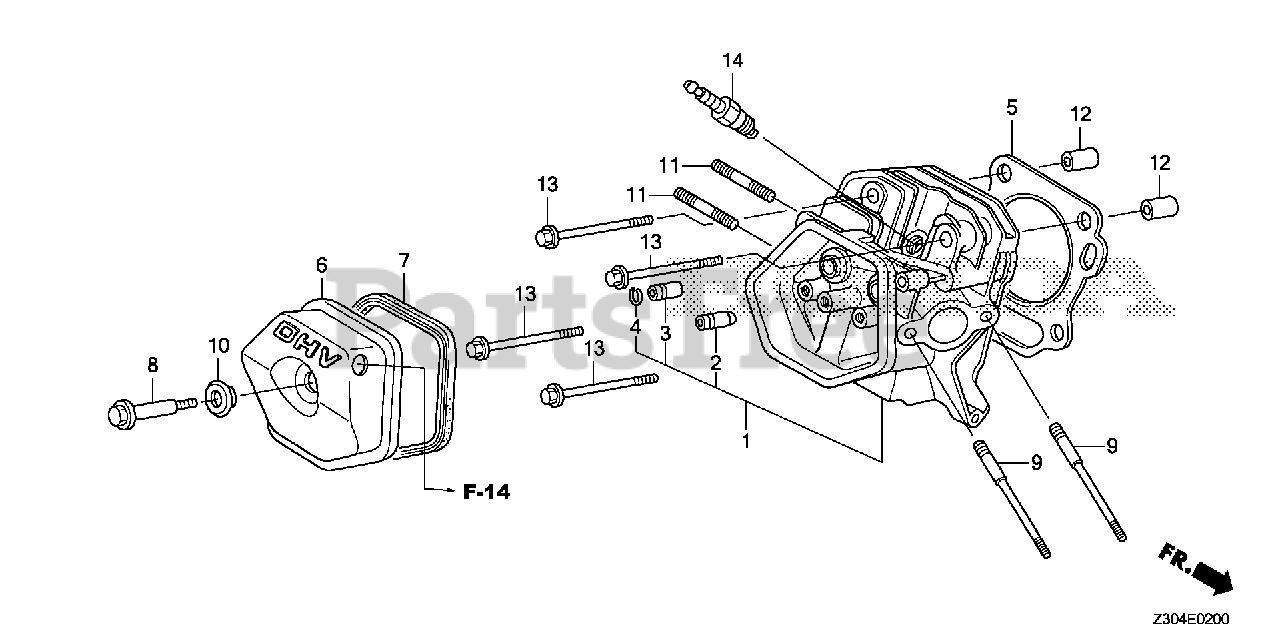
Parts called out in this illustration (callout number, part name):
1	CYLINDER HEAD
2	GUIDE, VALVE (OVER SIZE)
3	GUIDE, EX. VALVE (OVER SIZE)
4	CLIP, VALVE GUIDE
5	GASKET, CYLINDER HEAD (NIPPON LEAKLESS)
6	COVER, HEAD
7	GASKET, HEAD COVER
8	BOLT, HEAD COVER
9	BOLT, STUD (8X115)
10	WASHER, HEAD COVER
11	BOLT, STUD (8X32)
12	PIN, DOWEL (12X20)
13	BOLT, FLANGE (10X80)
14	SPARK PLUG (BPR5ES) (NGK)
